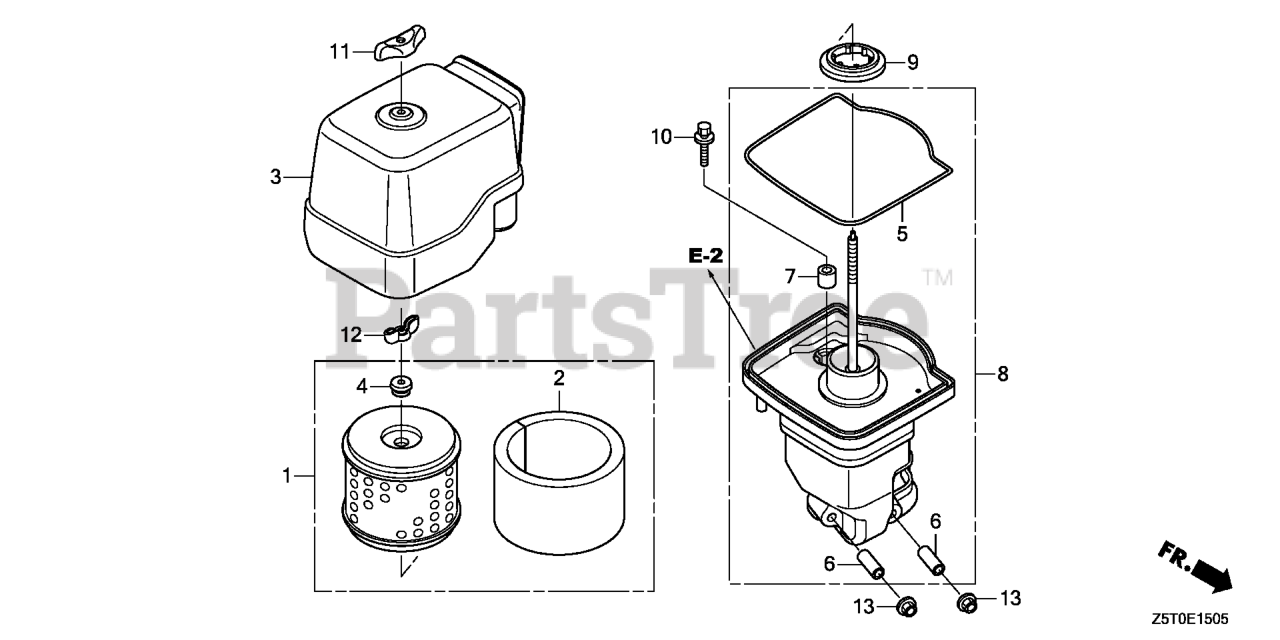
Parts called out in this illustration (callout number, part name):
1	ELEMENT, AIR CLEANER
2	FILTER (OUTER)
3	COVER ASSY., AIR CLEANER (CYCLONE)
4	GROMMET, AIR CLEANER
5	SEAL, AIR CLEANER COVER
6	COLLAR, AIR CLEANER
7	COLLAR B, AIR CLEANER
8	ELBOW, AIR CLEANER
9	GASKET, AIR CLEANER HOUSING
10	BOLT-WASHER (6X22)
11	NUT, AIR CLEANER
12	WINGNUT, TOOL BOX SETTING
13	NUT, FLANGE (6MM)
